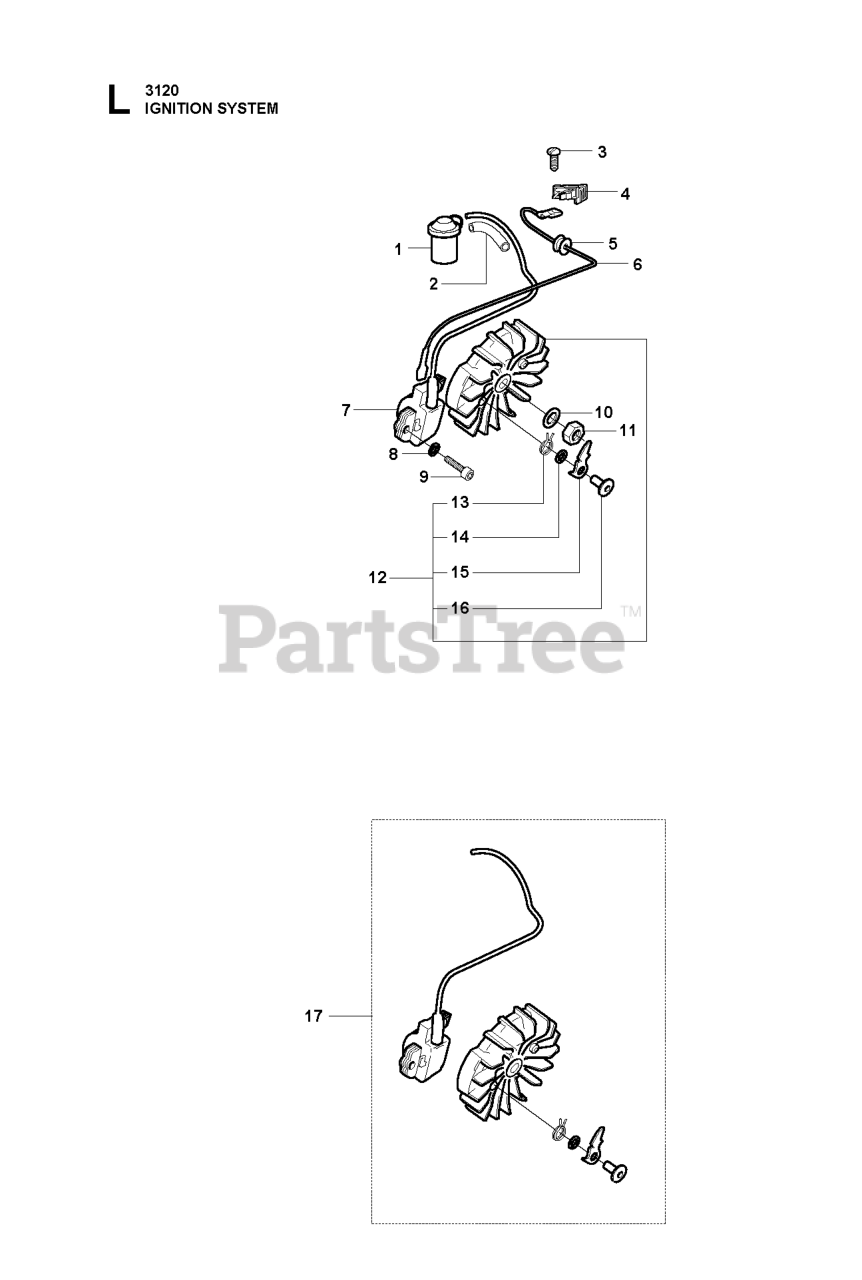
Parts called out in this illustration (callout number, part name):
1	SPARK PLUG CONN. KIT
4	SWITCH ON/OFF
7	IGNITION MODULE
8	WASHER 4.2X9
10	SPRING WASHER 10.5X18
12	FLYWHEEL
12	FLYWHEEL CPL
16	SCREW M5X14
17	Ignition Module
